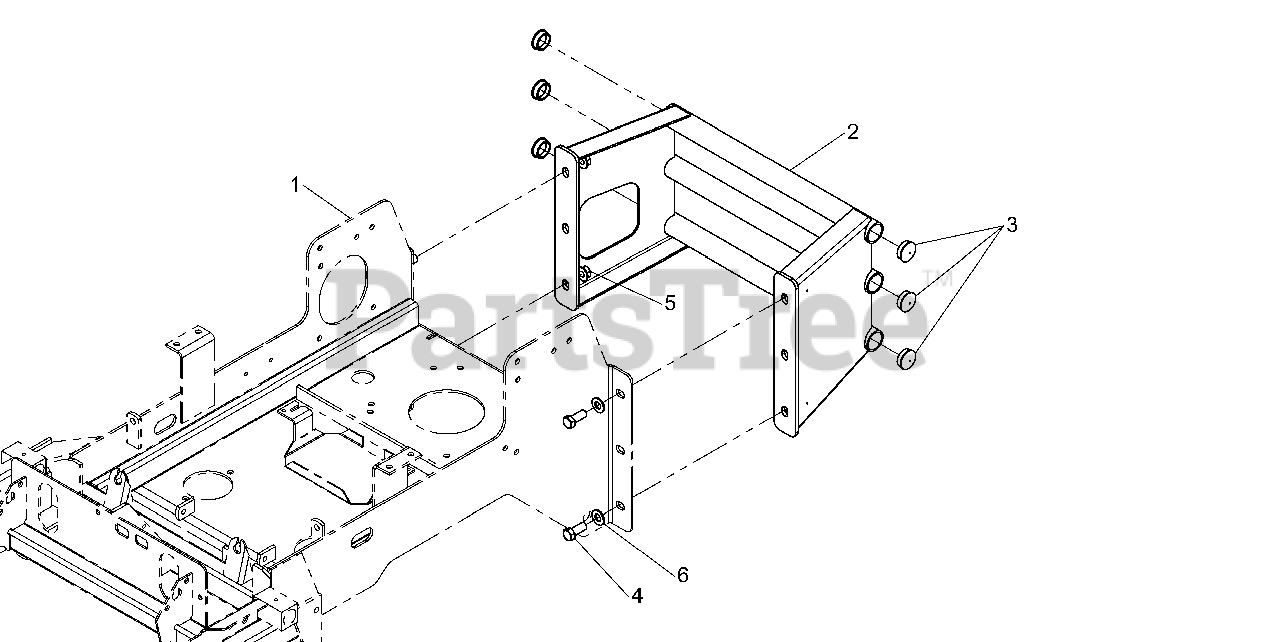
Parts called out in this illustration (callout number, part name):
1	MAIN FRAME (See Main Frame Group)
3	PLUG, PANEL, 1.25 BLACK
4	BOLT, 1/2-20 X 1-1/4"
5	NUT, 1/2-20 Hex Nylock Flange
6	WASHER, 1/2" SAE
